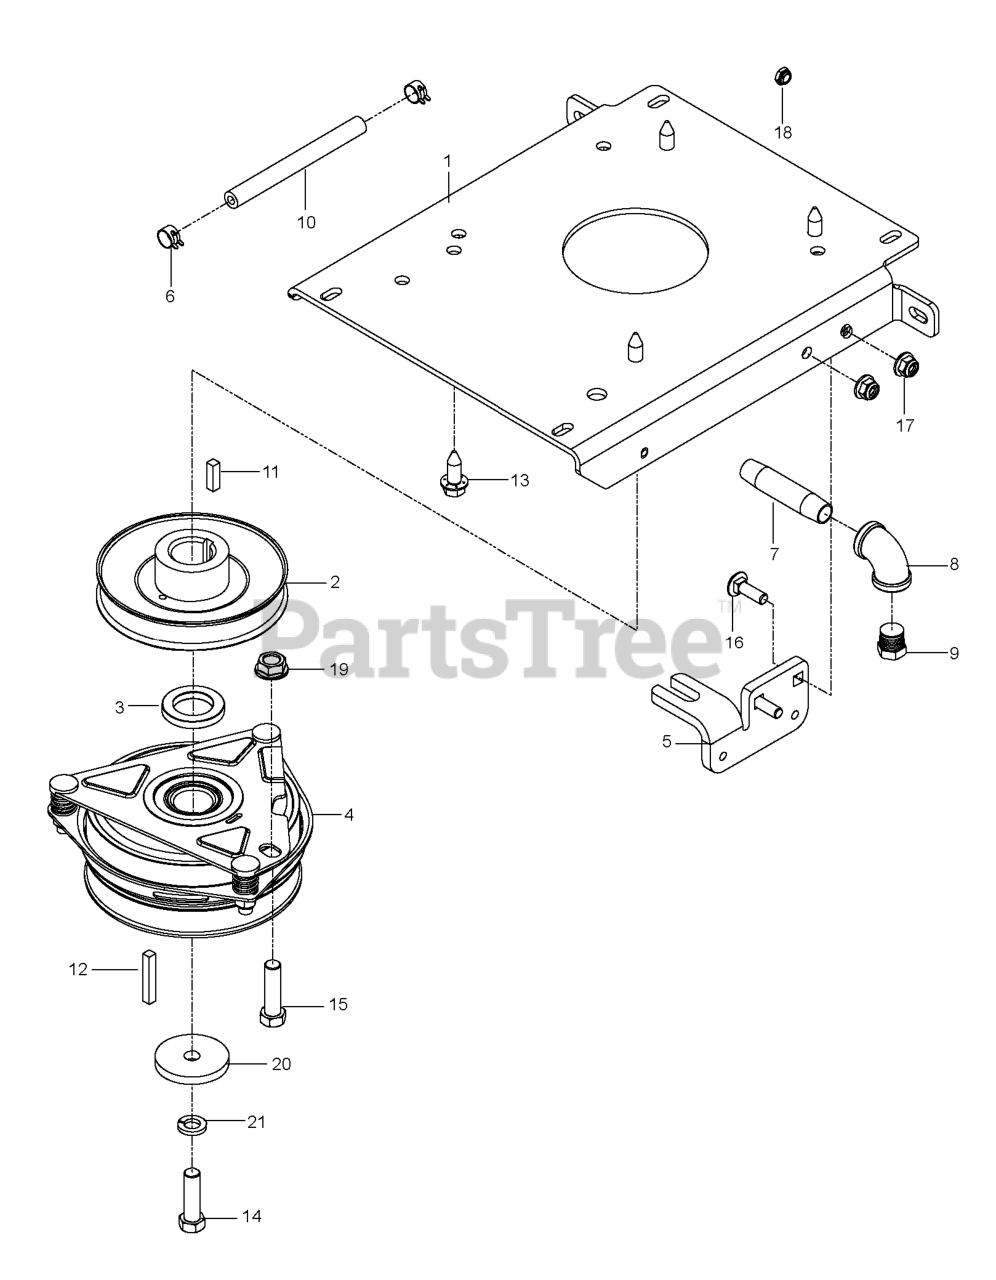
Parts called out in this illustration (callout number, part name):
1	PLATE.ENGINE.BLACK
2	PULLEY, ENGINE
3	SPACER, .25 X 1.135 I.D.
4	CLUTCH, 150 FT/LBS
5	STOP, CLUTCH, OGURA
6	HOSE CLAMP
7	PIPE NIPPLE 3/8 X 3
8	90 DEG.ELBOW 3/8NPT
9	PLUG, DRAIN 3/8 NPTF
10	HOSE.1/4".LOW.PERM.FUEL.LN.10"
11	KEY 1/4 SQ X 1.0
12	KEY 1/4 SQ X 2
13	SCREW 3/8-16X1
14	CLUTCH BOLT7/16-20X1.5GR5.96HR
16	RHSNB 5/16C X 1
17	5/16-18 NYLOC FLANGE NUT
18	JAM NUT 1/4C (2 2 PW01)
19	NUT 7/16C WHIZ
20	BLADE WASHER
21	WASHER 7/16 LOCK
